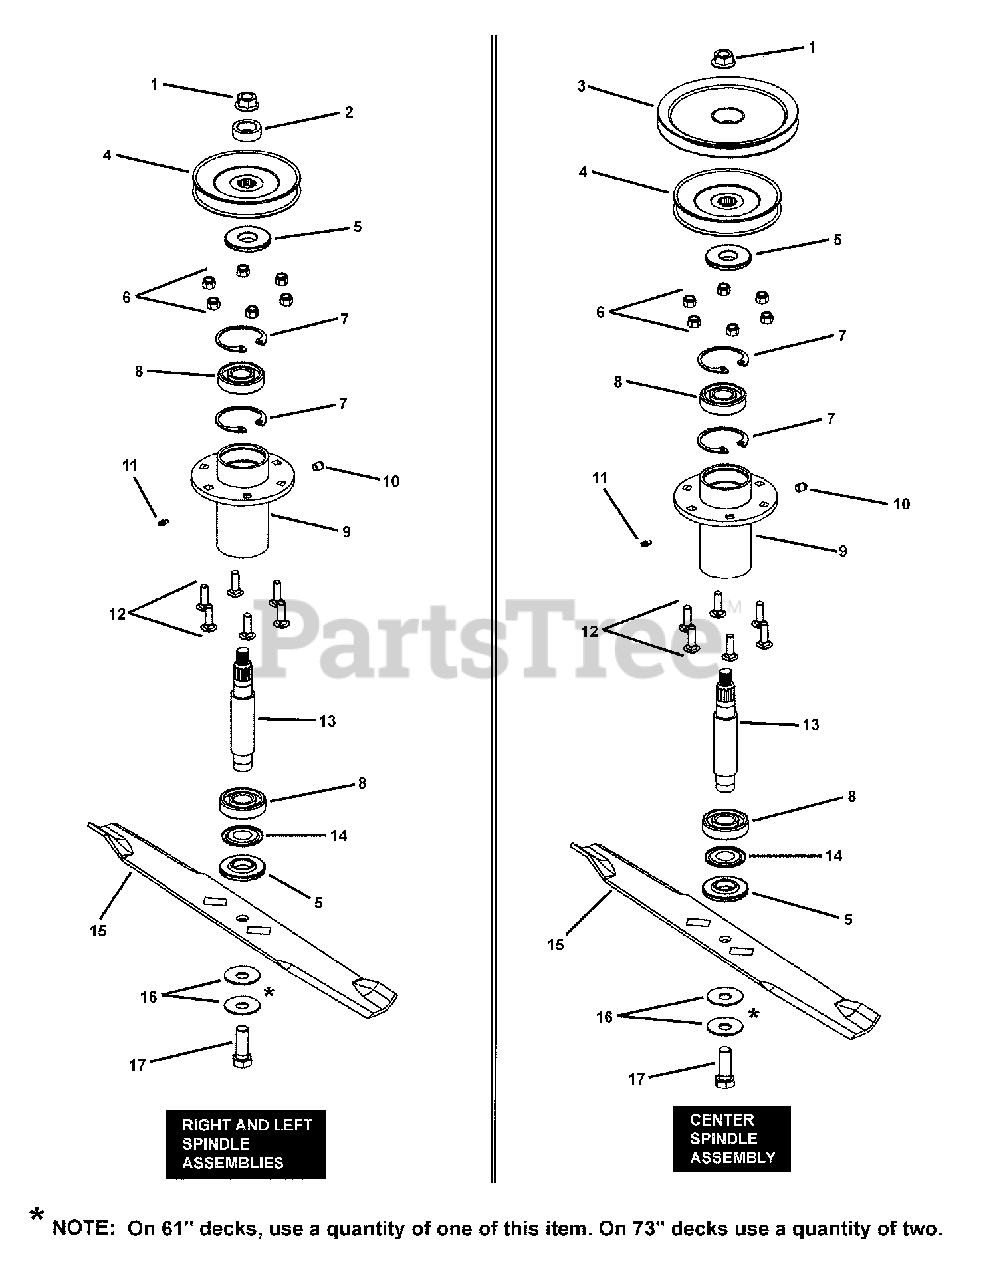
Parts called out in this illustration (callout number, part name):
1	NUT, 5/8-11 Hex Flange Lock, GR 5
2	WASHER, Spindle
3	PULLEY, Driven (61" Deck only)
3	PULLEY- Driven (73" Deck only)
4	PULLEY, 5.75" Diameter
5	WASHER, Spindle
6	NUT, 3/8-16 HEX NYLON LOCK
7	RETAINING RING, Internal
8	BALL BEARING (double sealed, double shield)
9	WELDMENT, 48" Spindle
10	VENT, Spindle (Alemite # 321839)
11	LUBE FITTING, 1/4-28 Straight
12	BOLT, 3/8-16 x 1" Square Neck Carriage, GR 5
12	BOLT, 3/8-16 x 1-1/4" Square Neck Carriage, GR 5
13	SPINDLE SHAFT (5/8-11 threads)
14	SEAL, Nylos
15	BLADE, 21" (61" Deck only)
15	BLADE, 25" (71" Deck only)
16	WASHER, Beveled
17	SCREW, 5/8-11 x 1-3/4" Hex Head Cap, GR 5
